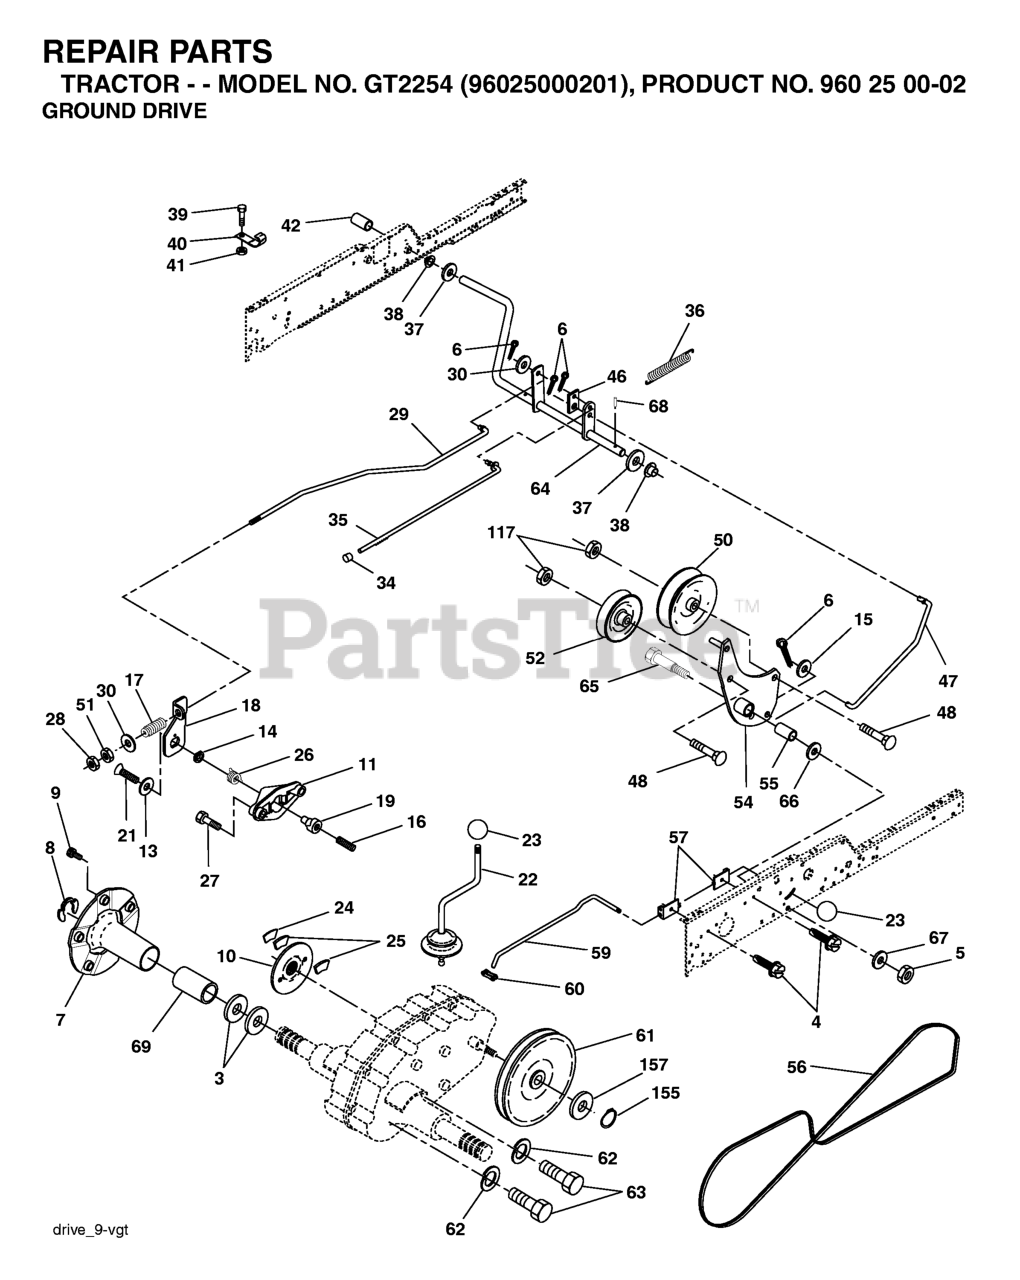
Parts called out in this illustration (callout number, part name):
4	Screw 5/16-18 x 1/2 Hex, Self Tapping 5/16-18 x 1/2
6	COTTER PIN
7	HUB.WHL.ASM.REAR
8	Ring, Klip Truarc #5304-75
10	DISC BRAKE
11	YOKE-BRAKE DISC
15	WASHER
17	SPRING,ROD BRAKE
18	BRAKE LEVER
19	BRAKE DISC CAM
21	Screw, Flat Head 1/4-28 x 3/4
22	LEVER.ASM.SHIFT
23	KNOB T (3/8 HOLE)
24	BRAKE PUCK SUPPORT
25	BRAKE PUCK TOP
26	RETURN SPRING
28	NUT
29	ROD BRAKE ZINC GT
30	WASHER
34	PLUNGER CAP
35	PARKING BRAKE ROD
36	SPRING DRIVE GROUND
39	Screw, Fin. #10-24 x 1
40	ACTUATOR INTERLOCK SWITCH
41	Nut Centerlock 10-24 unc
42	PEDAL COVER T
46	RETAINER SPRING
47	CLUTCH ROD
48	BOLT.3/8-16X1.50
50	FLAT IDLER PULLEY
51	NUT
52	PULLEY.IDLER.V.
55	BEARING LT (2 2)
56	V-BELT GROUND DRIVE
57	BRACKET SHIFT ROD
59	ROD SHIFT HI LO
60	CONNECTING LINK
61	PULLEY.TRANSAXLE
62	LOCKWASHER
64	SHAFT CLUTCH/BRAKE PEDAL
65	BOLT.SHLDR.3/8-16
66	WASHER.BLADE
67	WASHER
68	ROLL PIN STD
69	COVER.HUB.BLACK
117	NUT LOCK FLG 3/8-16 UNC
155	RETAINING RING LT
157	THRUST WASHER
